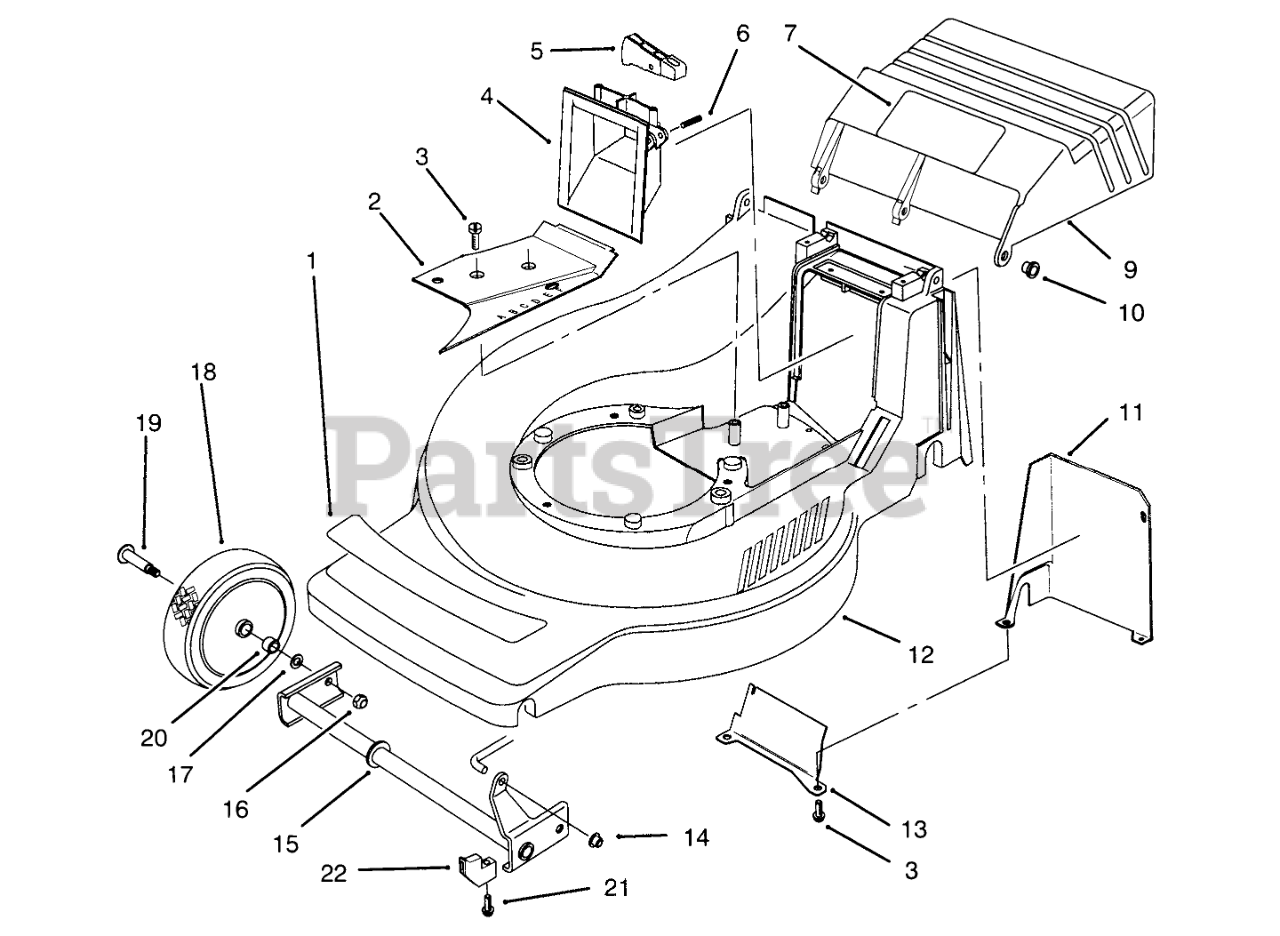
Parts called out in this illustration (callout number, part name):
1	DECAL - DECK
2	COVER - BELT
3	SCREW-RH
4	GRIP - LOWER
5	TRIGGER - HOC
6	PIN-SPIRAL
7	DECAL-DANGER
9	Door-Discharge
10	BUSHING-DOOR
11	COVER - SHIELD
12	HOUSING - 43 CM
13	BAFFLE-BAGGER, REAR
14	NUT-PUSH
15	AXLE-FRONT
16	NUT-LOCK
17	WASHER
18	WHEEL-FRONT
19	WHEEL BOLT
20	BUSHING
21	SCREW-RETAINER
22	RETAINER - AXLE
